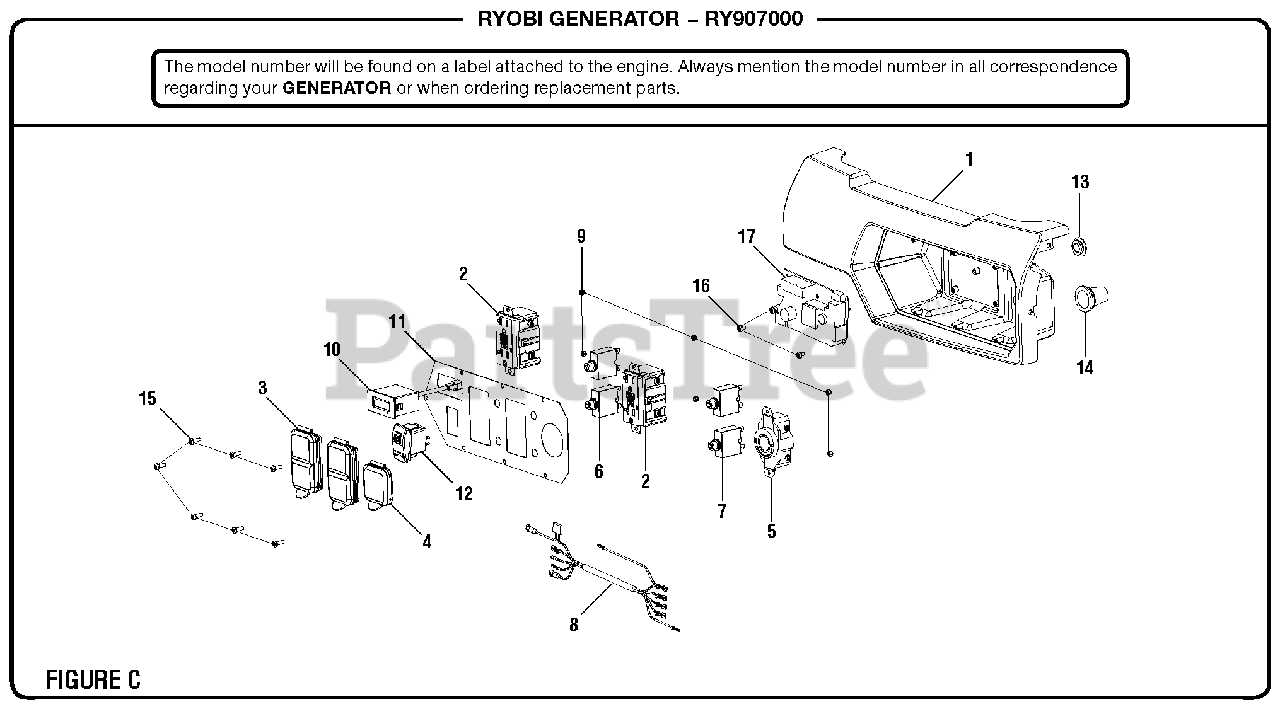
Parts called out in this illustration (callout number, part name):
1	Control Box
2	120 Volt GFCI Receptacle
3	GFCI Receptacle Cover
4	Receptacle Cover (30 Amp)
5	120 Volt Twist Lock Receptacle (30 Amp)
6	Circuit Breaker (20 Amp)
7	Circuit Breaker (30 Amp)
8	Wiring Harness
9	Lock Nut (#6-32)
10	Digital Display
11	Faceplate
12	Start/Stop Switch
14	Rubber Boot
15	Screw (8-18 x 1/2 in.)
16	Screw (M3 x 5 mm)
17	Circuit Board Assembly
